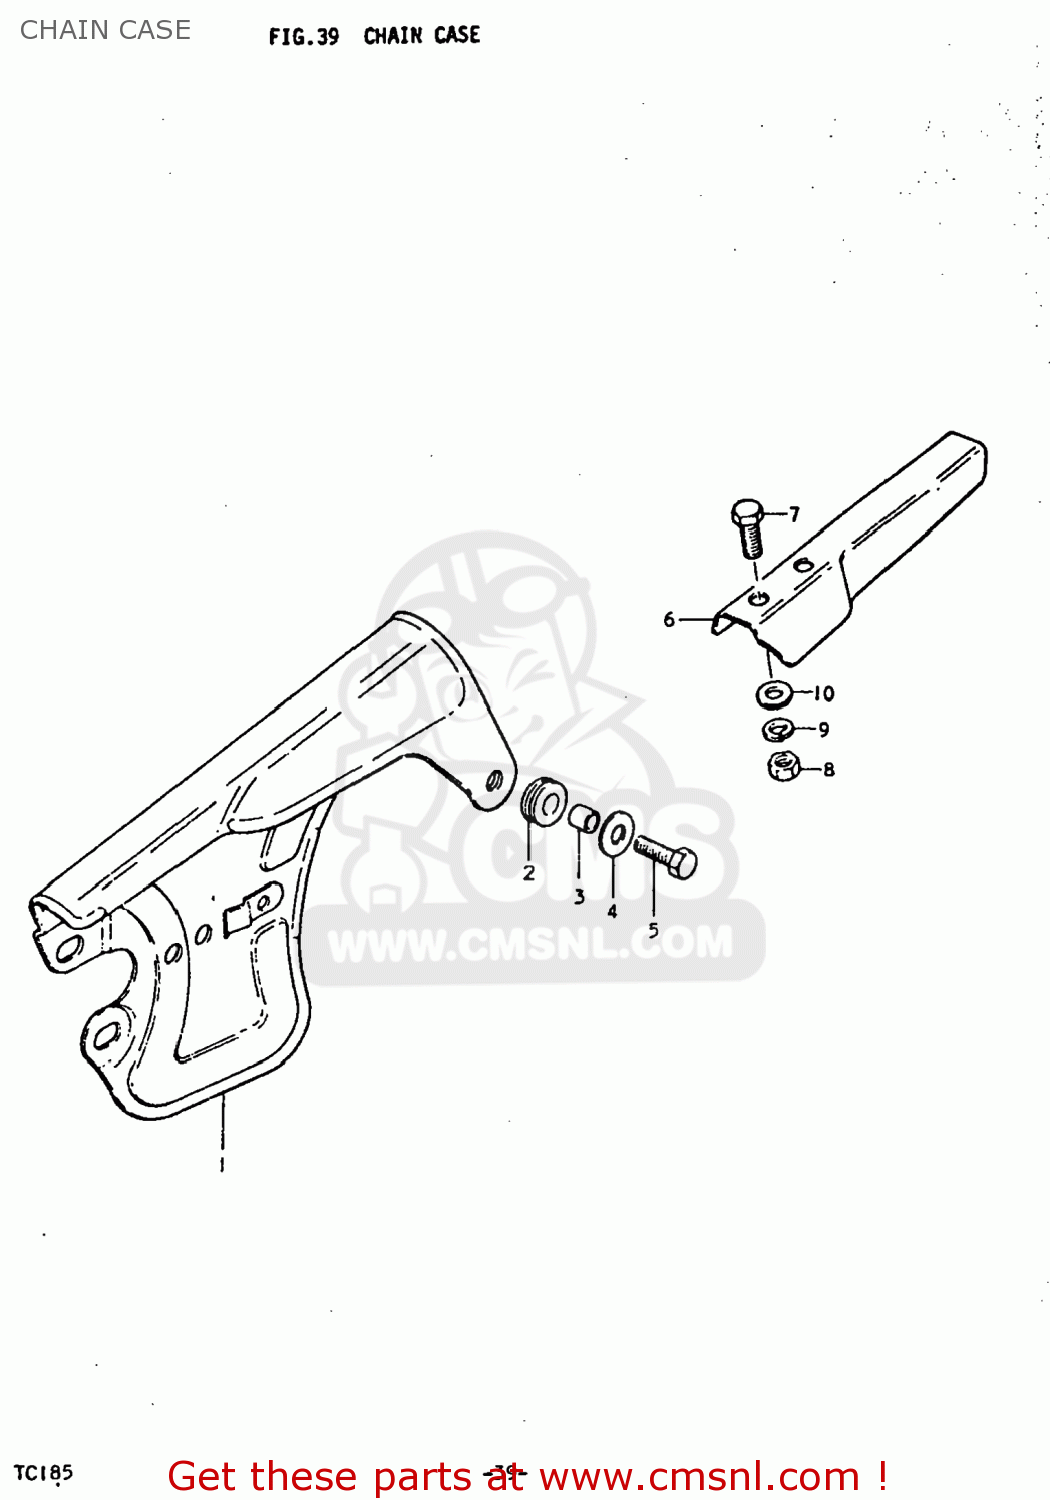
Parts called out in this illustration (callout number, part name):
1	CASE,CHAIN
2	CUSHION
3	SPACER (7X9X7)
4	WASHER (6.5X20X1.2)
5	BOLT
7	BOLT
8	NUT
9	LOCK WASHER
10	WASHER
